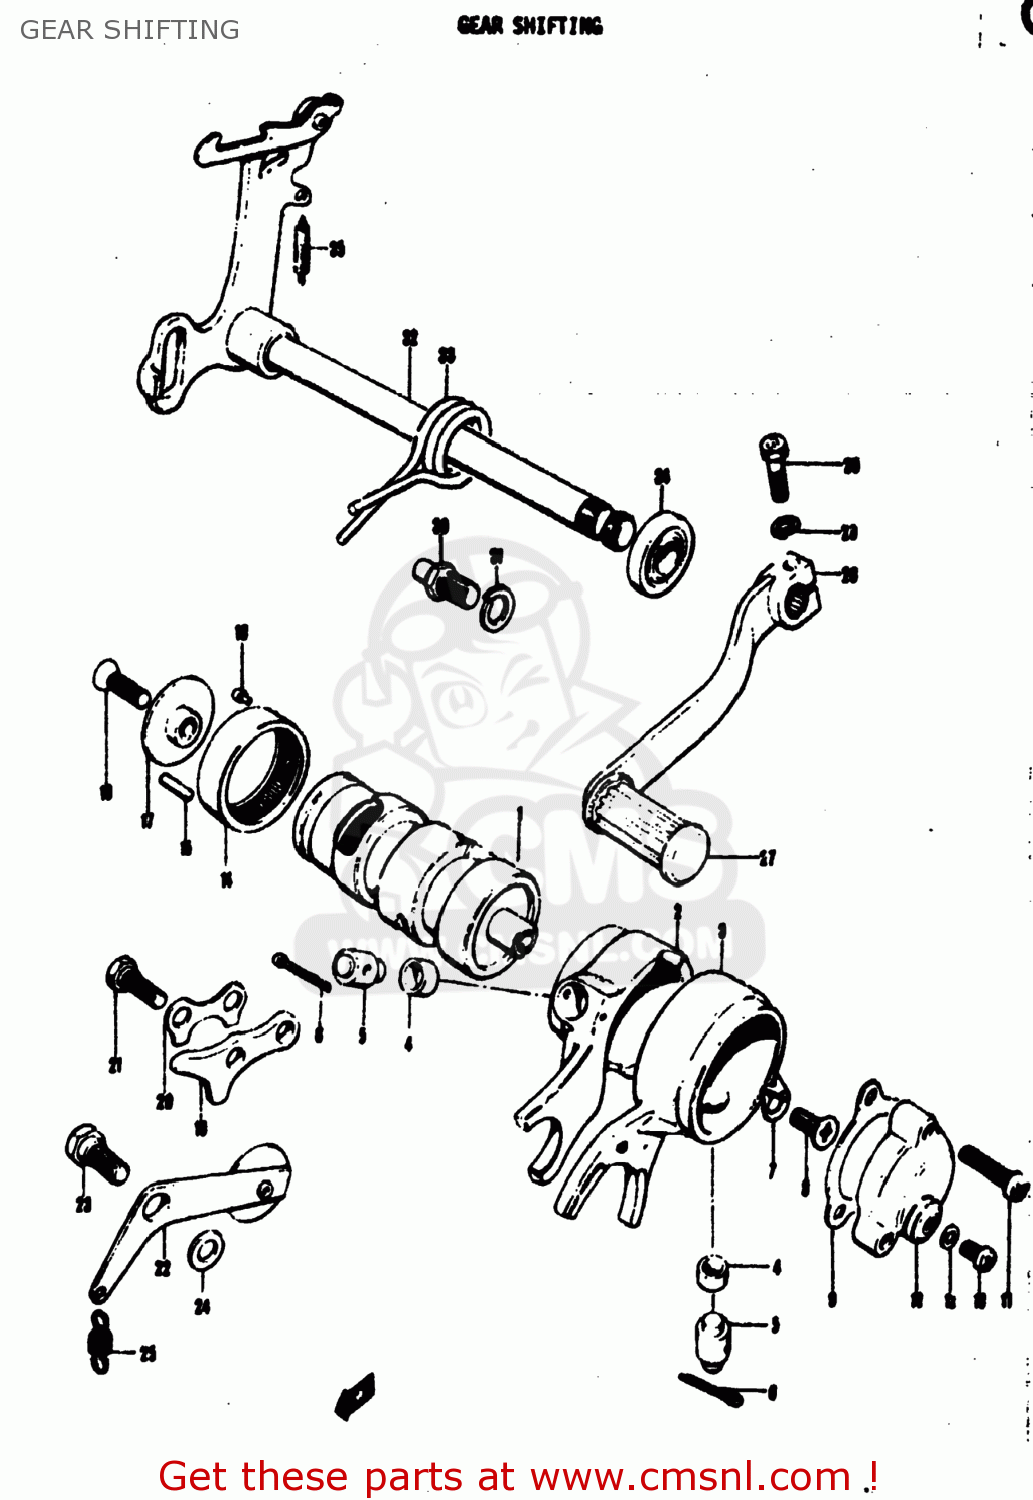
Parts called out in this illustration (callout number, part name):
1	CAM, GEAR SHIFTING
2	HIGH SPEED GEAR SHIFTING
3	FORK, LOW SPEED SHIFTING
4	SPACER
5	PIN
6	PIN 25X20
7	POINT,NEUTRAL INDICATOR SWITCH CON
8	SCREW
9	GASKET,GEAR SHIFT SWITCH (NAS)
10	SWITCH,NEUTRAL INDICATOR
11	SCREW
12	WASHER
13	CROSS HEAD SCREW
14	BEARING(31.7X38.1X12.7)
15	ROLLER(4X13.8)
16	PIN (2)
17	RETAINER,GEAR SHIFT CAM
18	SCREW
19	GUIDE, CAM
20	WASHER
21	BOLT
22	GEAR SHIFTING CAM STOPPER
23	BOLT(6X16.1)
24	WASHER
25	SPRING
26	LEVER ASSEMBLY,GEAR SHIFTING
27	RUBBER,GEAR SHIFT PEDAL
28	BOLT
29	LOCK WASHER
30	STOPPER,GEAR SHIFT ARM
31	LOCK WASHER
33	SPRING
34	OIL SEAL
35	SPRING
